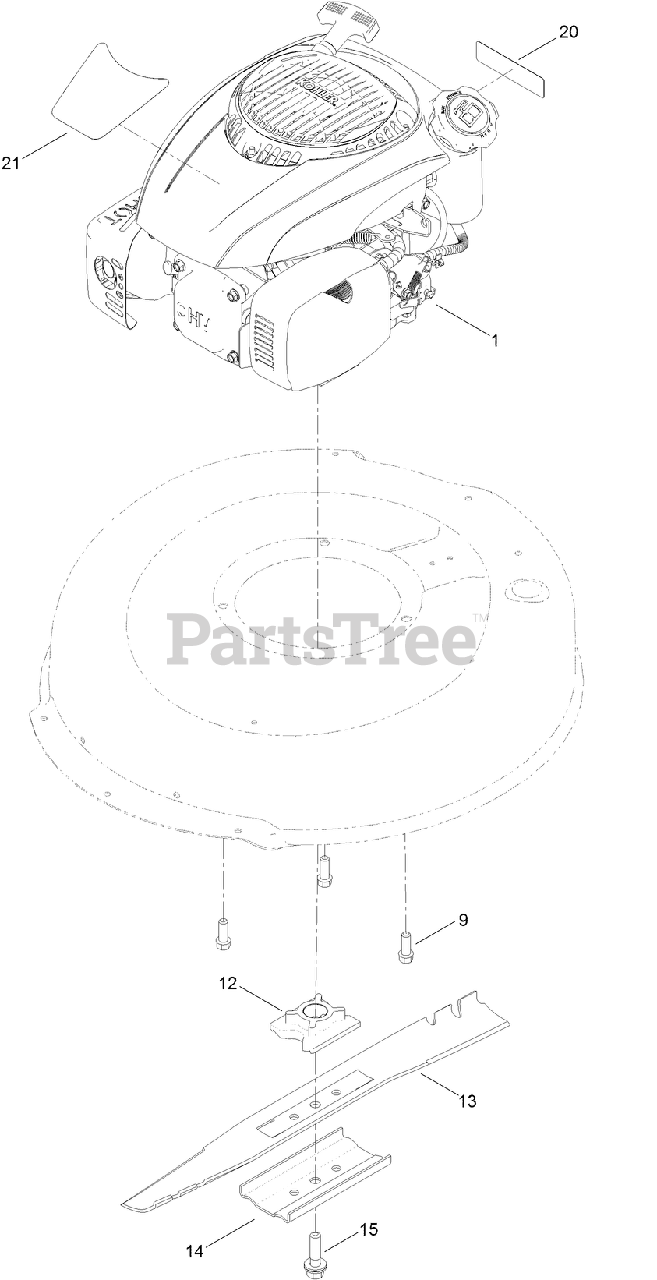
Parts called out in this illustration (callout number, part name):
9	SCREW-TAPTITE
12	RETAINER-BLADE
14	SUPPORT-BLADE
15	BOLT-BLADE
20	DECAL-ARRESTER, SPARK
